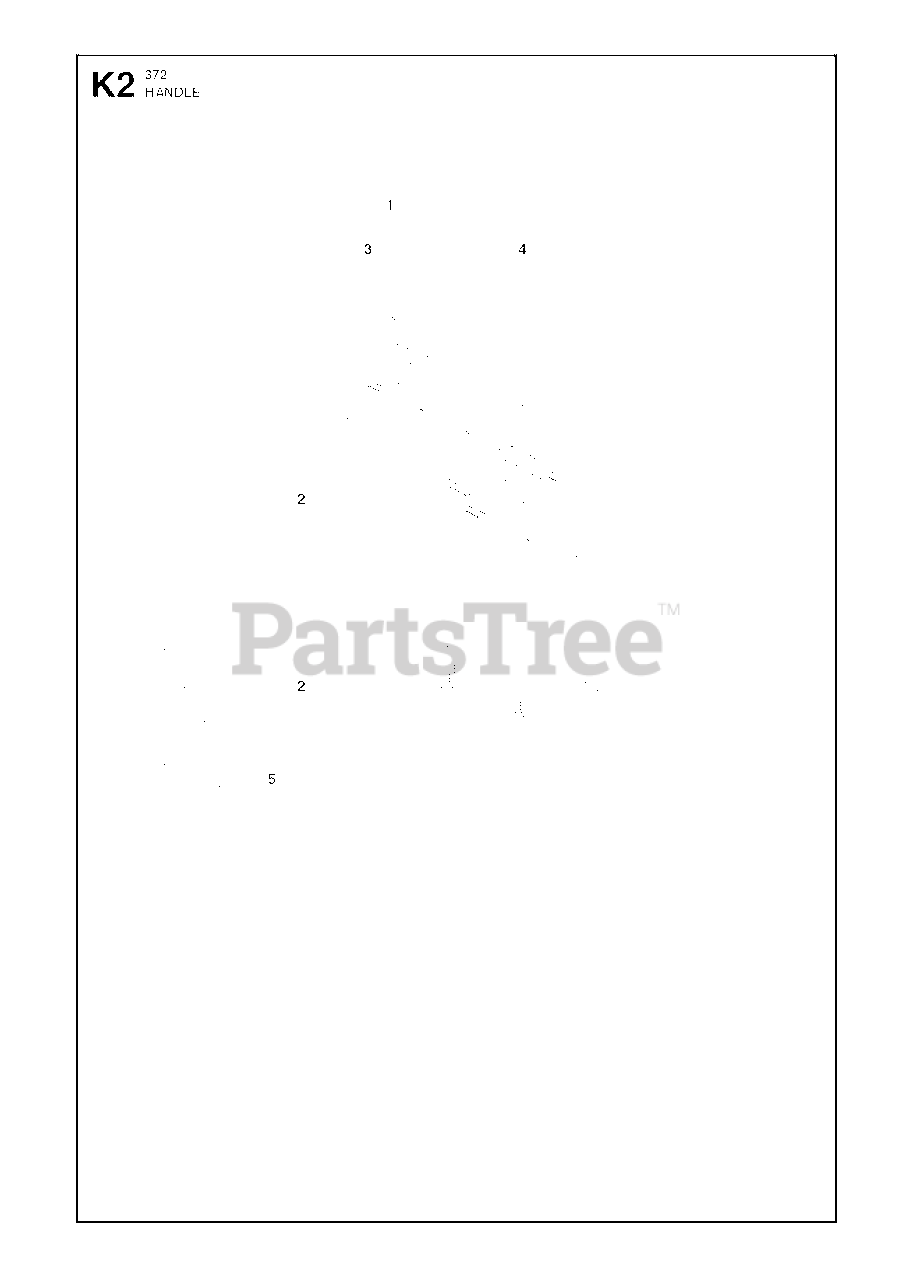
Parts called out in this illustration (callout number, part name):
1	FRONT HANDLE/WRAP
1	HANDLE, HTD WRAP 372
2	SCREW
3	SCREW
4	ANTIVIBE MOUNT
5	FELLING DOG
